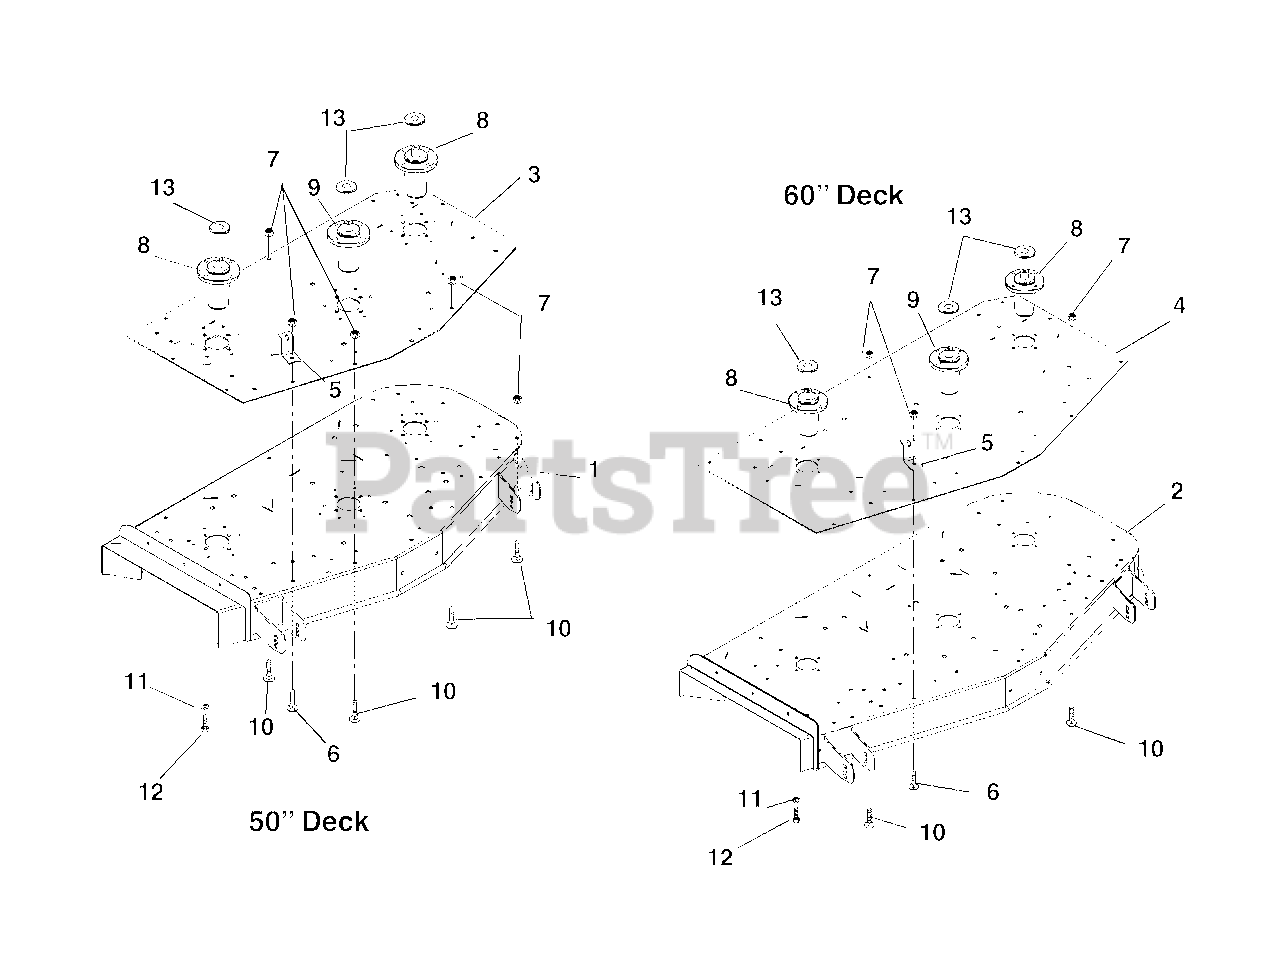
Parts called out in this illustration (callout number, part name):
1	Weldment, 50"Deck (Side Discharge)
2	Weldment, 60" Deck (Side Discharge)
3	Plate, 50" Reinforcement
4	Plate, 60" Reinforcing
5	Anchor, Spring
6	Bolt-Round Head Square Neck .38-16 x 1.25 Grade 2
7	Nut-Locking-Nylon .38-16 (50" Deck)
7	Nut-Locking-Nylon .38-16 (60" Deck)
8	Assembly, Spindle L-Hub
9	Spindle Assembly (Center)
10	Bolt-Round Head Square Neck .38-16 x 1.00 Grade 2 (50" Deck)
10	Bolt-Round Head Square Neck .38-16 x 1.00 Grade 2 (60" Deck)
11	Washer-Locking .38 x .094
12	Bolt-Hex .38-16 x 1.00 Grade 5
13	Slinger-Dust
